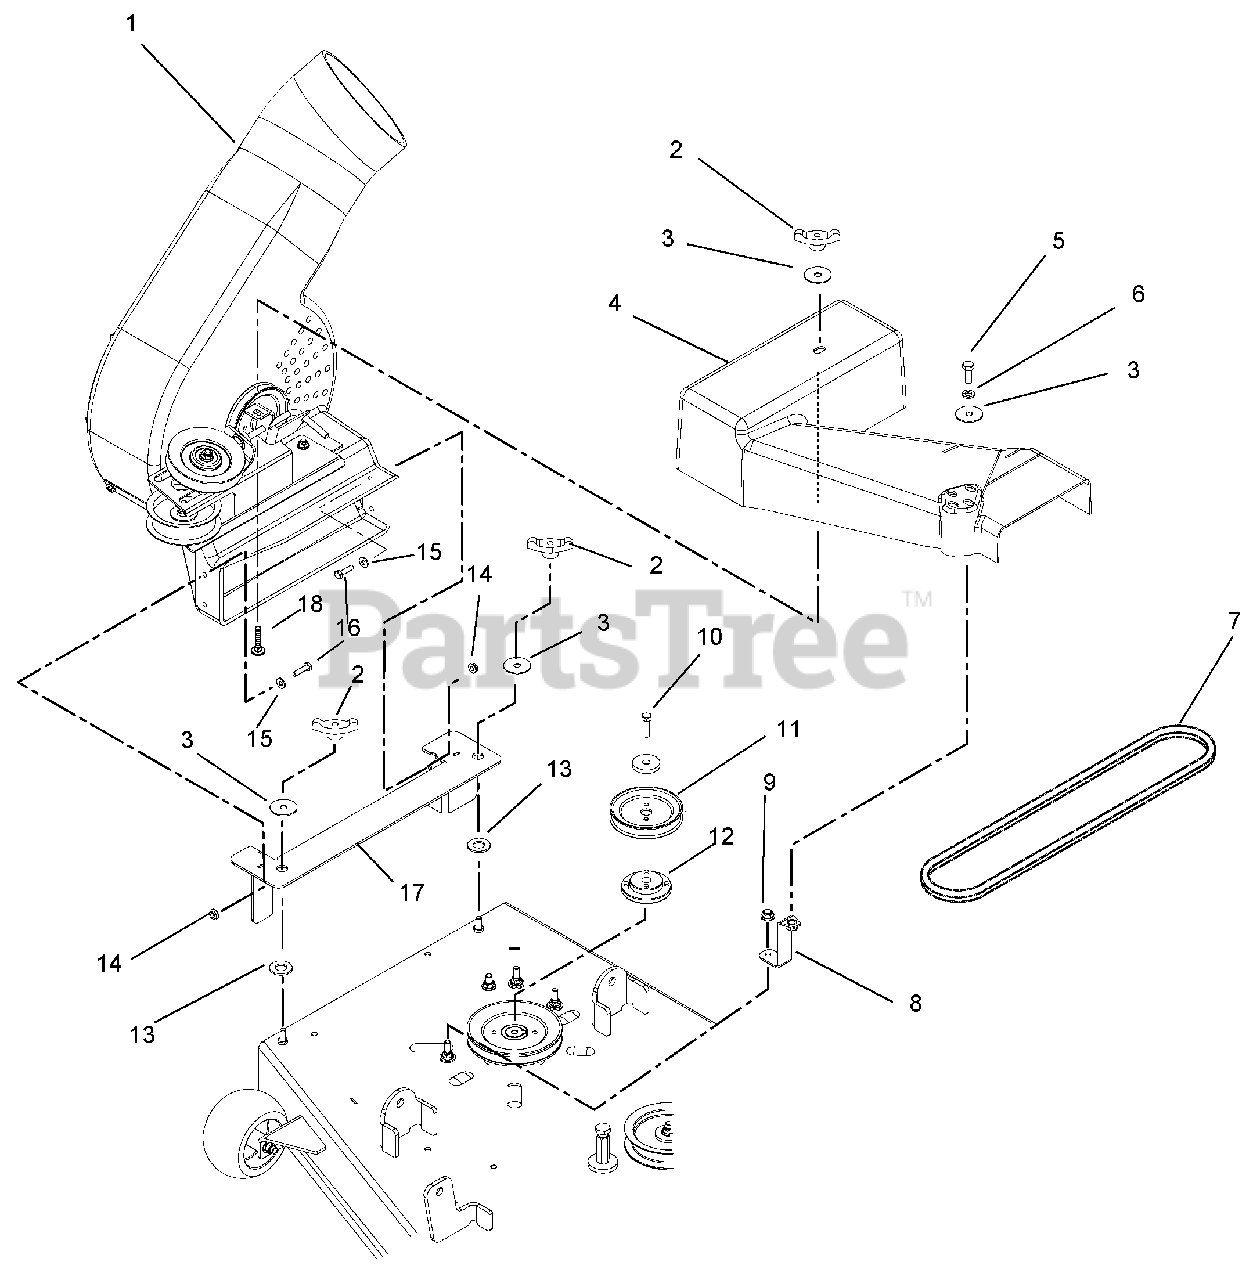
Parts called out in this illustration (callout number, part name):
1	BLOWER (SERVICE ASSEMBLY)
2	KNOB-CLAMPING, .312-18 NYLOC
3	WSHR-FL-STL .380X1.50X.062 YWZ
4	BELT COVER W/DECAL
5	@BLT-HEX .38-16X1.00 GR5 YWZC
6	@WSHR-LK .38X.094 REG YWZC
7	V-BELT, 4L-RAW EDGE
8	WMT, XL BLOWER COVER STANDOFF
9	@NUT-LK-NYL-FLG .31-18 YWZC
10	BLT-HEX .38-16X1.75 GR8 M-EPYZ
11	SHEAVE, 4.00 DIA.
12	ASSEMBLY, SHEAVE ADAPTER
13	WSHR-FL-STL .656X1.250X.10 YZC
14	@NUT-LK-NYL-FLG .25-20 YWZC
15	@WSHR-FL-STL.281X.62X.065 YWZC
16	@BLT-HEX .25-20X1.00 GR5 YWZC
17	WMT, BLOWER BRACKET
18	@BLT-RDHDSQNK .31-18X1.50 G5YZ
